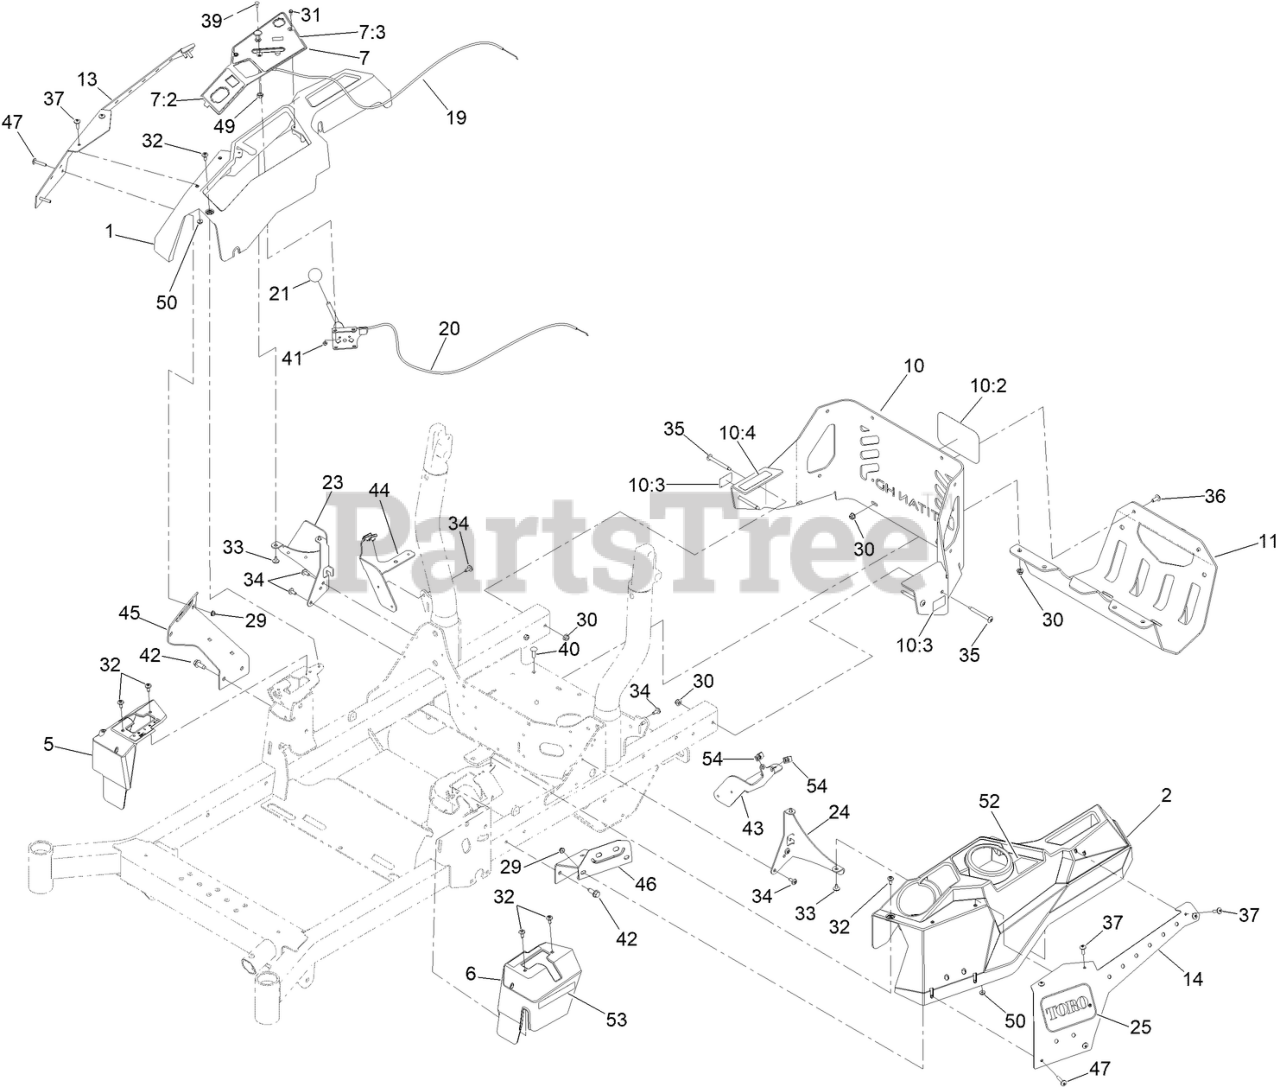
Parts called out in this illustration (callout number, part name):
1	CONSOLE-RH
2	CONSOLE-LH
5	COVER-CONTROL, MOTION (RH)
6	COVER-CONTROL, MOTION (LH)
7	CONTROL PANEL ASM
7:2	DECAL-PANEL, CONTROL
7:3	DECAL-PANEL, CONTROL
10	REAR GUARD ASM
10:2	DECAL
10:3	DECAL-WARNING
10:4	DECAL-ARRESTER, SPARK
11	GUARD-MUFFLER
13	COVER-POD, RH
14	COVER-LH
19	CABLE-CONTROL, CHOKE
20	CABLE-CONTROL, THROTTLE
21	KNOB-BALL
23	SUPPORT-CONSOLE, RH
24	BRACKET-CONSOLE, LH
25	DECAL
29	NUT-HF
30	NUT-HF, NI
31	SCREW-HWH
32	SCREW-SHOULDER
33	SCREW-TORX
34	SCREW-TORX
35	SCREW-TORX
36	SCREW-TORX
37	SCREW-TRUSS
39	BOLT-CARR
40	SCREW-CARR
41	NUT-LOCK, NI
42	SCREW-FORMING, THREAD
43	BRACKET-SUPPORT, LEFT POD
44	BRACKET-SUPPORT, RIGHT POD
45	BRACKET-SUPPORT, POD (RH)
46	BRACKET-SUPPORT, POD (LH)
47	SCREW-TRUSS
49	NUT-HJ
50	NUT-KEPS
52	DECAL-FILL, FUEL
54	NUT-RETAINER
